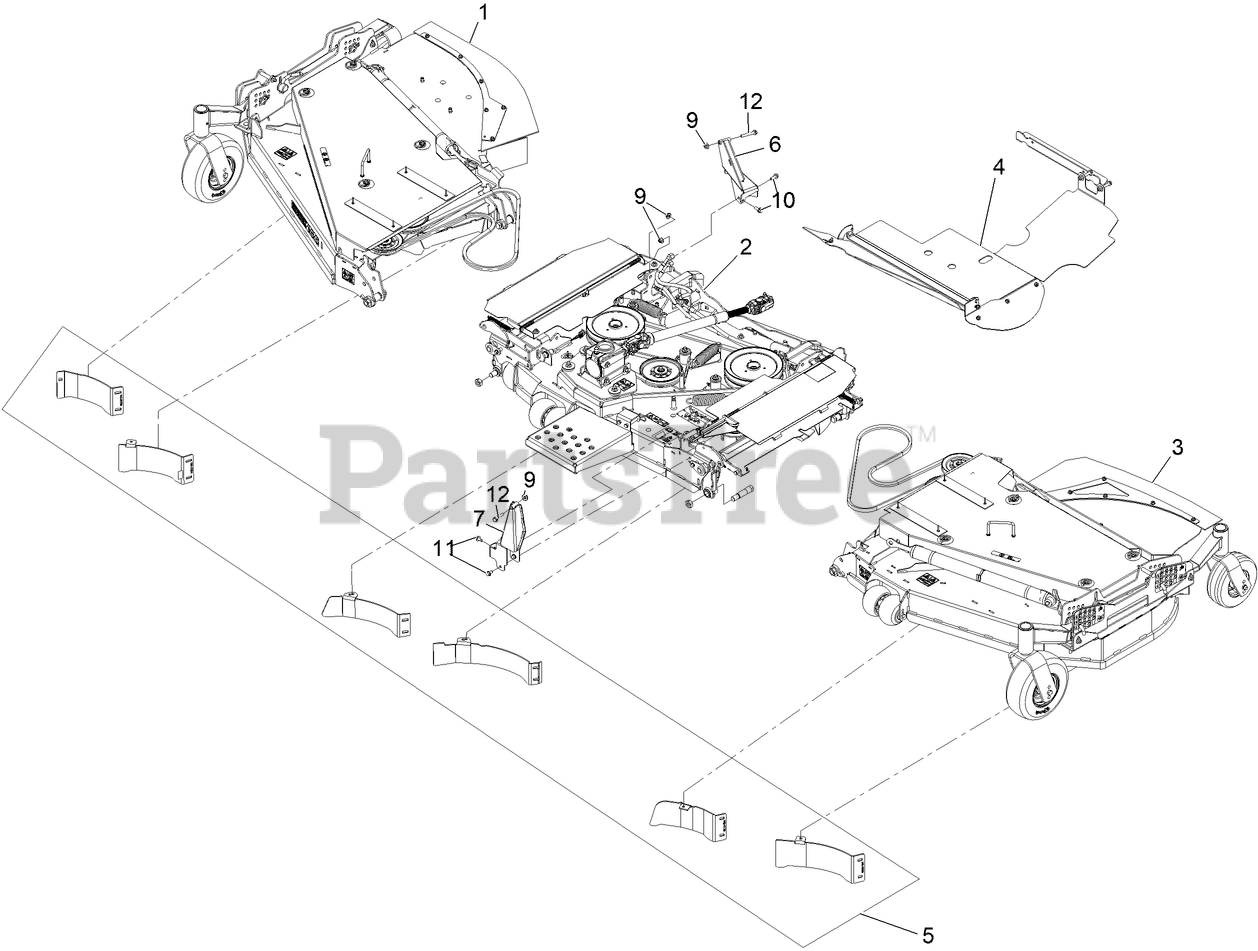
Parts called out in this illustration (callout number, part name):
1	ASM-Deck, RH Wing
1	ASM-Deck, RH Wing 144E
2	ASM-Deck, Ctr
2	ASM-Deck, Ctr 144E
3	ASM-Deck, LH Wing
3	ASM-Deck, LH Wing 144E
5	KIT-FINISH CUT BAFFLE 144
6	Weld-RH Spring Mount-Upstop
7	Bracket, LH Centerdeck-Spring [bl
9	Nut-Nyloc 3/8-16 Flg
10	SCREW-HHF 3/8-16 X 1
11	SCREW-HWH
12	Screw-HHF
